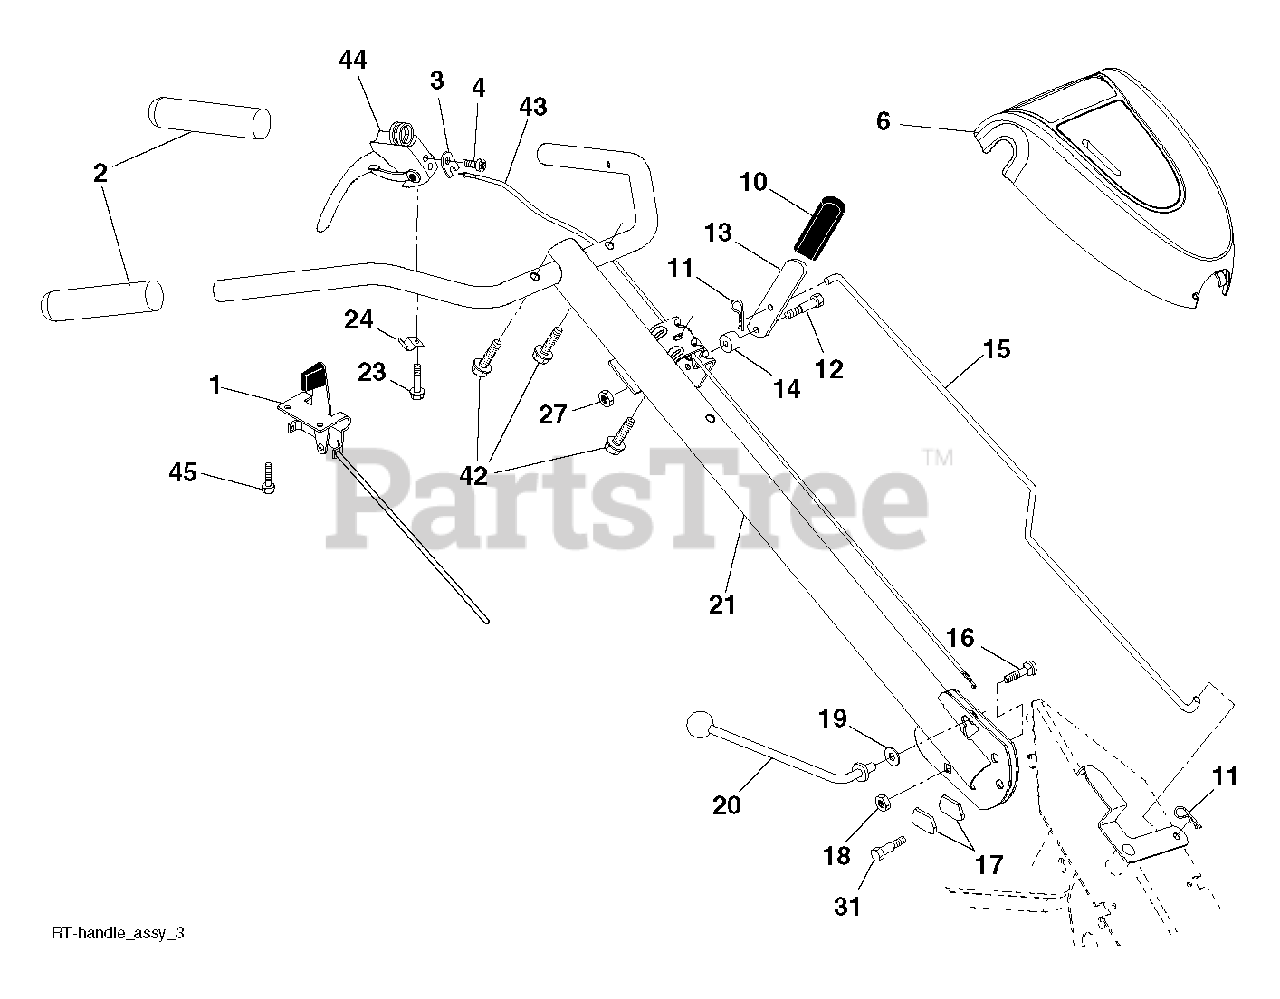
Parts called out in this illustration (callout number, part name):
1	CONTROL.THROTTLE.SNAP.IN
2	GRIP.1X5.06
3	CLIP.RETAINER.CABLE.BZP
4	SCREW.TORX.#10-14X1/2
10	GRIP T
11	RETAINER M
12	SHOULDER BOLT ST
14	GROMMET.RUBBER.CRT.TILLER
15	ROD, SHIFT
18	LOCKNUT
19	WASHER CRT
20	LEVER.LOCK.CRT
21	Curved Plow Handle Assembly for Tiller, Black
23	TAPPING SCREW
24	CLIP.PLATED
27	NUT T
31	BOLT.PIVOT
42	SCREW.#10 X 0.750.BOS THREAD
43	CABLE.HANDLE.TINE.CONTROL.CE
45	SCREW.#10 X 0.500
